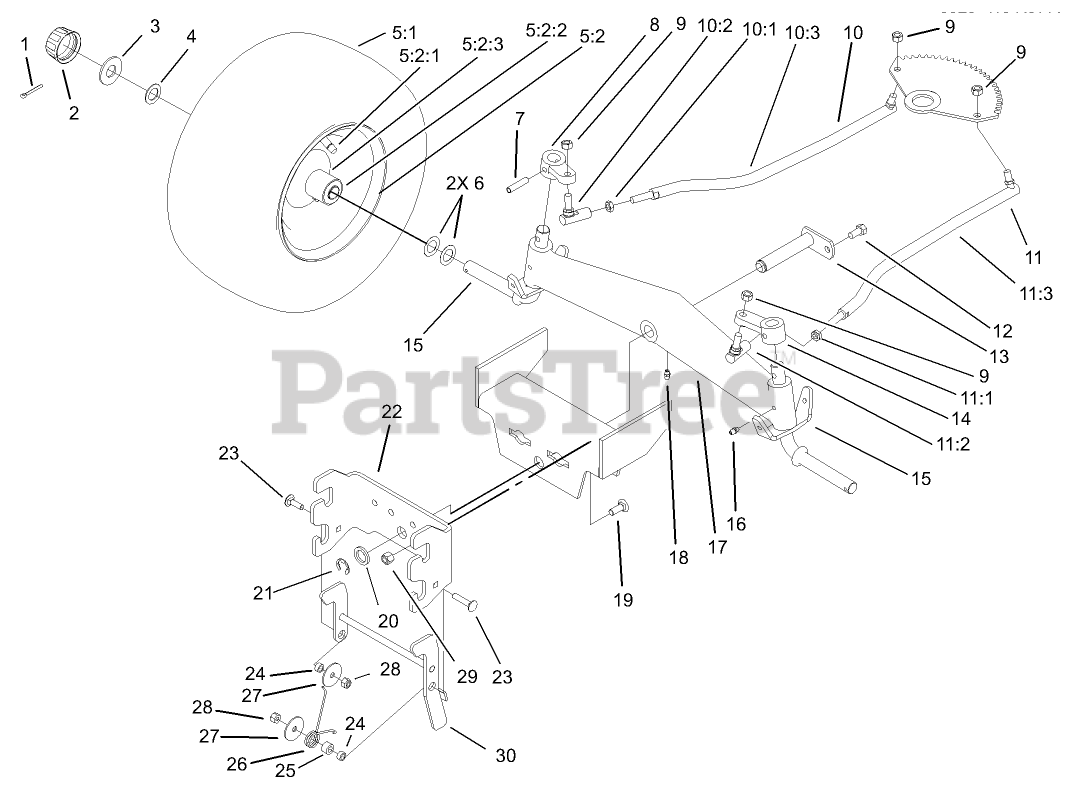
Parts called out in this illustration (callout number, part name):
1	PIN-COTTER
2	CAP-HUB
3	WASHER-PLAIN
4	WASHER
5	FRONT WHEEL TIRE ASM
5:2	WHEEL ASM
5:2:1	VALVE
5:2:2	BEARING-WHEEL
5:2:3	ZERK-GREASE
6	WASHER-SHIM
8	ARM-SPINDLE, LH
10	LINKAGE-STEERING, RH
11	LINKAGE-STEERING, LH
12	SCREW-HWH, TAPTITE
13	PIN-AXLE
14	ARM-SPINDLE, RH
15	SPINDLE
16	FITTING-GREASE
17	AXLE-FRONT
18	FITTING-LUBE, 45 DEG
19	BOLT-CARR
20	WASHER
21	E-RING
23	BOLT-CARR
24	SPACER-YOKE, RIGHT
25	SPACER
26	SPRING-TORSION
27	WASHER-FLAT
28	NUT-LOCK, NI
29	NUT-LOCK, NI
30	LATCH ASM
